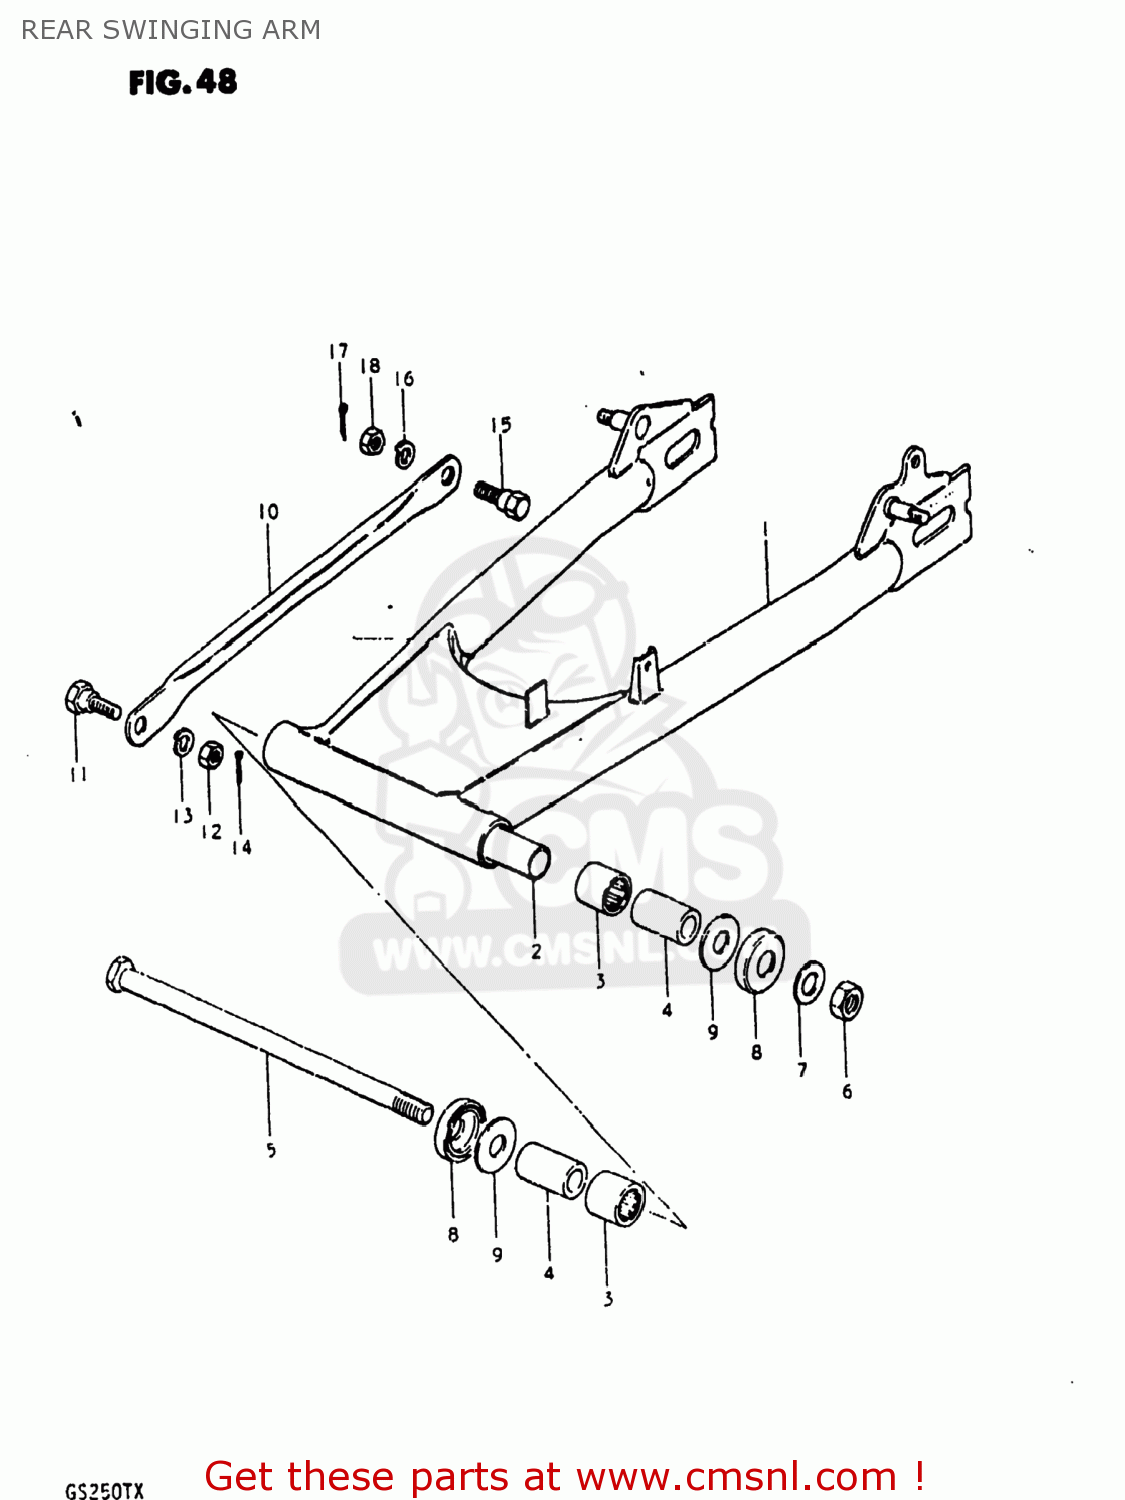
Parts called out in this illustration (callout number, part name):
1	SWING ARM ASSEMBLY,REAR
2	SPACER,SWINGINGARM CTR
3	BEARING(22X29X30)
4	SPACER,RR SWGARM PIVOT
5	SHAFT,REAR SWING ARM
6	NUT 14MM
7	WASHER
8	CVR,RR SWGARM DUST SEAL(OD:40)
9	WASHER(14.2X34X1)
10	TORQUE LINK,REAR
11	BOLT(10X24.5)
12	NUT
13	LOCK WASHER
14	PIN
15	BOLT(10X31)
16	LOCK WASHER
17	PIN
18	NUT
